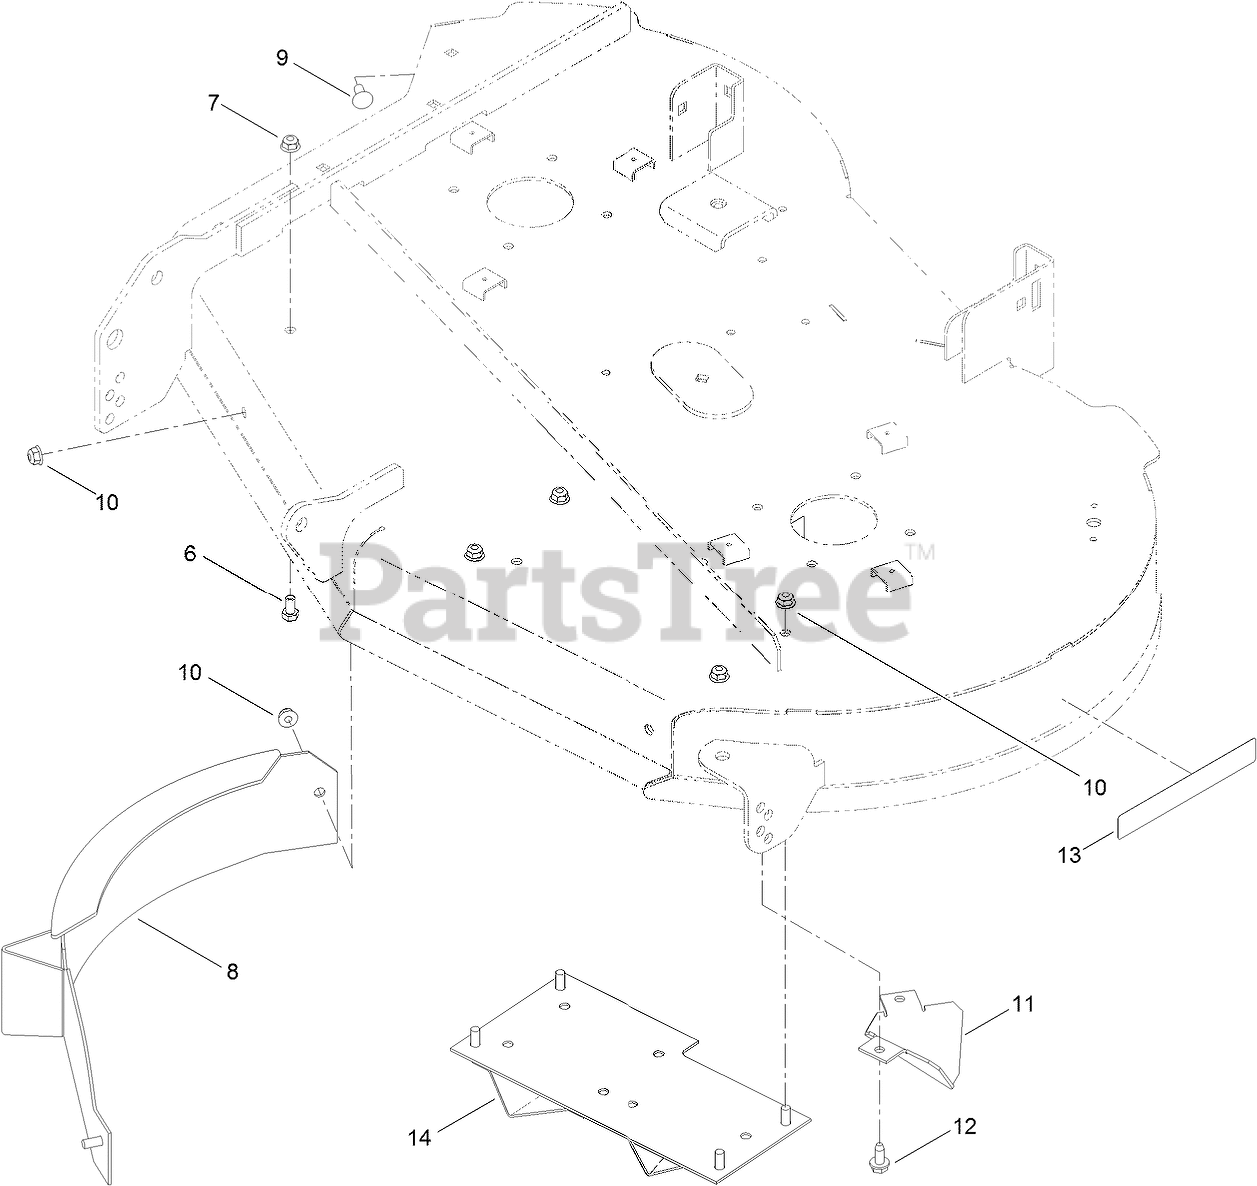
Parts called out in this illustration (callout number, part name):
6	SCREW-HH
7	NUT-HF, NI
8	BAFFLE ASM
9	BOLT-CARR
10	NUT-HF, NI
11	KICKER-FLANGED
12	SCREW-HWHTF
13	DECAL-RECYCLER
14	KICKER ASM
